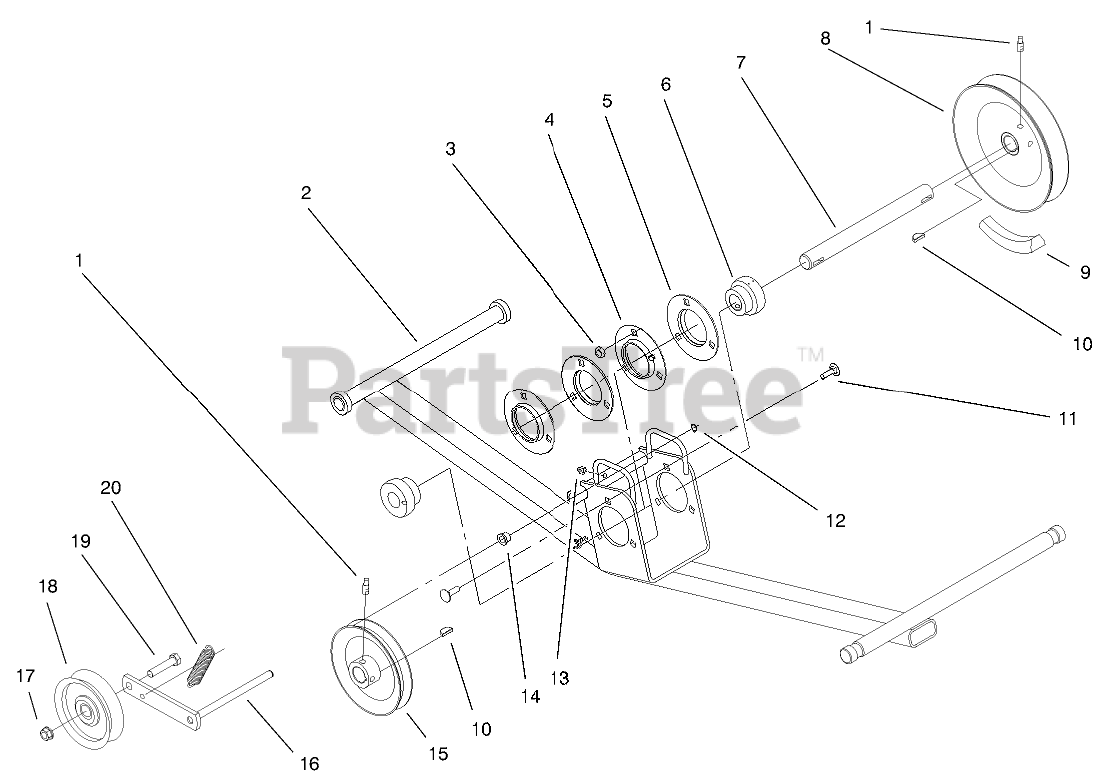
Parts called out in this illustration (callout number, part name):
1	SCREW-SQH
1	PIN-CLEVIS
2	WA - SUPPORT, JACKSHAFT
2	PIN-HAIR
3	NUT-LOCK, NI
4	FLANGE-ZERK RELUBE
5	Flange
6	BEARING AND COLLAR
7	SHAFT-JACK
8	PULLEY-DRIVE
9	V-BELT-FRONT
10	KEY-WOODRUFF
11	BOLT-CARR
12	RING-RETAINING
13	FITTING-GREASE
14	BUSHING-FLANGED
14	GUIDE-CABLE
15	PULLEY-V
16	WA - IDLER LEVER
17	NUT-LOCK, NI
18	PULLEY-IDLER, FLAT
19	SCREW-HH
20	SPRING-BRAKE
